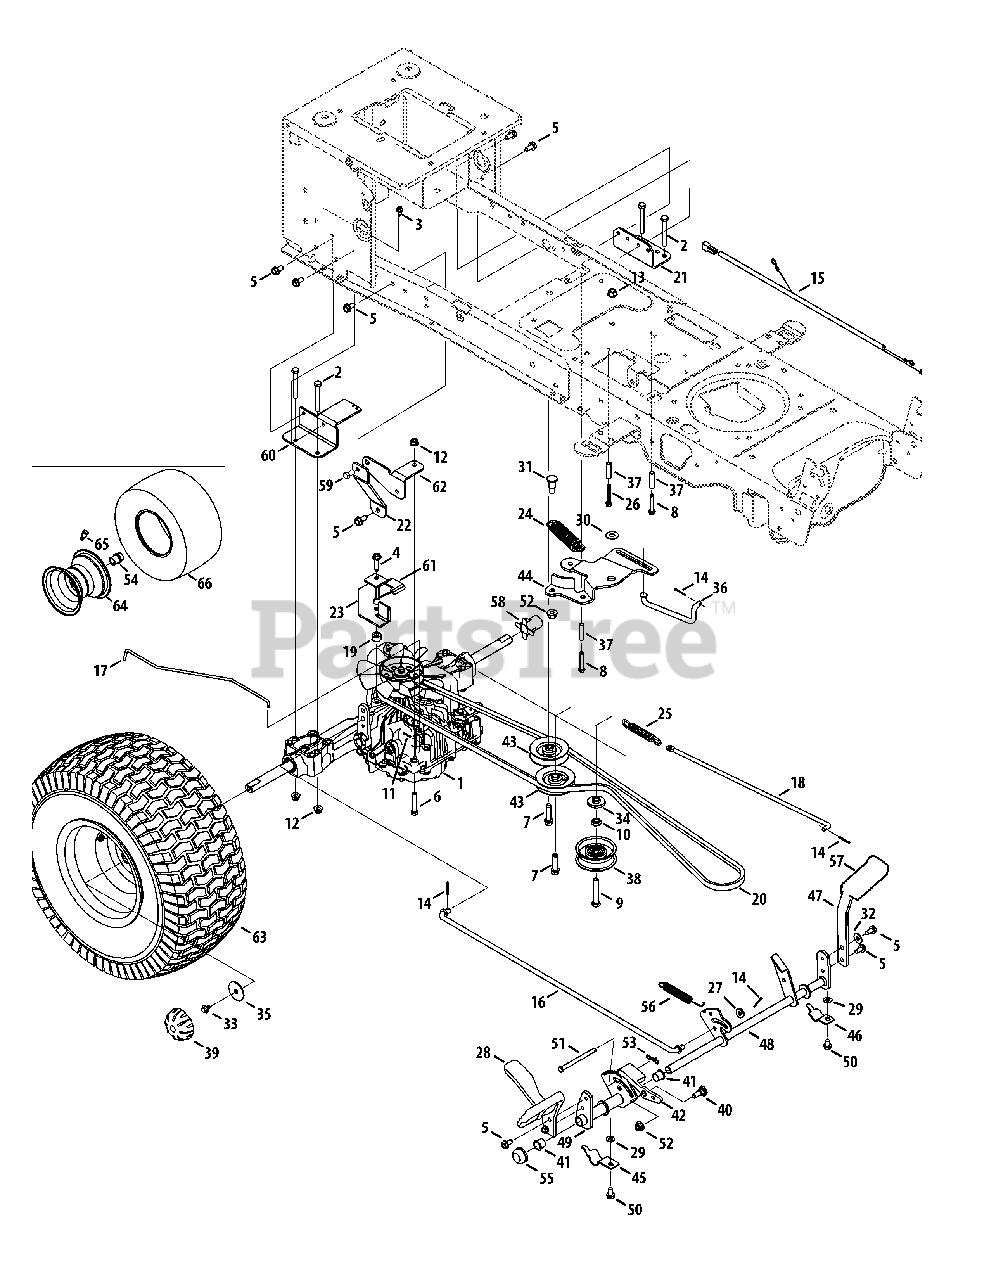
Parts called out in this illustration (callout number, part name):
1	Transmission, Tuff Torq K46
2	Hex Screw, 5/16-18, 2.50, Gr5, Std
3	Screw, Self-tapping, 1/4-20, 0.500
4	Screw, Self-tapping, 5/16-18, 1.250
5	Screw, Self-tapping, 5/16-18, .750
6	Hex Screw, 5/16-18, 1.75, Gr5
7	Screw, Self-tapping, 3/8-16, 1.500
8	Screw, Self-tapping, 1/4-20, 1.625
9	Hex Screw, 3/8-16, 2.25, Gr5
10	Nut, Jam, 7/16-20, Gr2
11	Pin, Cotter, 3/32, 1.0
12	Nut, Flange Lock, 5/16-18, Nylon
13	Nut, Flange Lock, 3/8-16
14	Pin, Cotter, 3/32, 1.0
15	Jumper Harness, Ground & Reverse
16	Rod, Control, Tuff-Torq
17	Rod, Hydro Bypass
18	Rod, Brake, NX9 Tuff-Torq
19	Spacer, .330 x .715 x .430
20	Belt, V-Type
21	Bracket, Mount, Tuff-Torq
22	Bracket, NX9 Tuff Torq
23	Bracket, Belt Keeper
24	Spring, Extension, 1.00 Dia x 4.75
25	Spring, Extension, .59 Od x 4.00
26	Screw, Self-tapping, 1/4-20 x 1.75
27	Washer, Flat, .375 x .738 x .063
28	Control Pedal
29	Washer, Flat, .344 x .688 x .065
30	Wash, Flat, .385 x 1.00 x .030
31	Scr, Shldr, .50 x .685 3/8-16
32	Washer, Bell, .340 x .872 x .060
33	Screw, 5/16-24 x .750
34	Spacer, Shoulder, 1.375 x .380 x .183
35	Washer, Flat, .350 x 1.59 x .062
36	Rod, Transmission, Bypass
37	Spacer, .260 x .372 x 1.420
38	Pulley, Idler, Flat 2.75 OD
39	Cap, Hub
40	Bolt, Shoulder, .500 x .270, 3/8-16
41	Bearing, Flange, .630 x .695 x .60
42	Latch, Cruise
43	Pulley, Idler, V-Type x 3.06
44	Bracket, Idler, Center Double
45	Bracket, Support, Pedal Strap
46	Bracket, Support, Pedal Strap 5/8
47	Bracket, Pedal, Brake
48	Control Assembly, Brake
49	Bracket Assembly, Pedal, Hydro
50	Screw, Self-tapping, 5/16-18, 0.625,
51	Pin, Clevis, 5/16 x 3.985
52	Nut, Flange Lock, 3/8-16, Nylon
53	Pin, Cotter, Bow-Tie 72
55	Cap, Push 5/8
56	Spring, Extension, .63 Dia x 4.95
57	Pad, Pedal, Brake
58	Sleeve, .765 Id x 1.500
59	Hex Cap Screw, 3/8-16 x .75
60	Bracket, Mount
61	Bracket, Belt
62	Bracket, Support
63	Wheel Assembly
64	Rim Assembly, Plastic Bead, 46"
65	Tubeless Air Valve
66	Tire, 20 x 8 x 8
